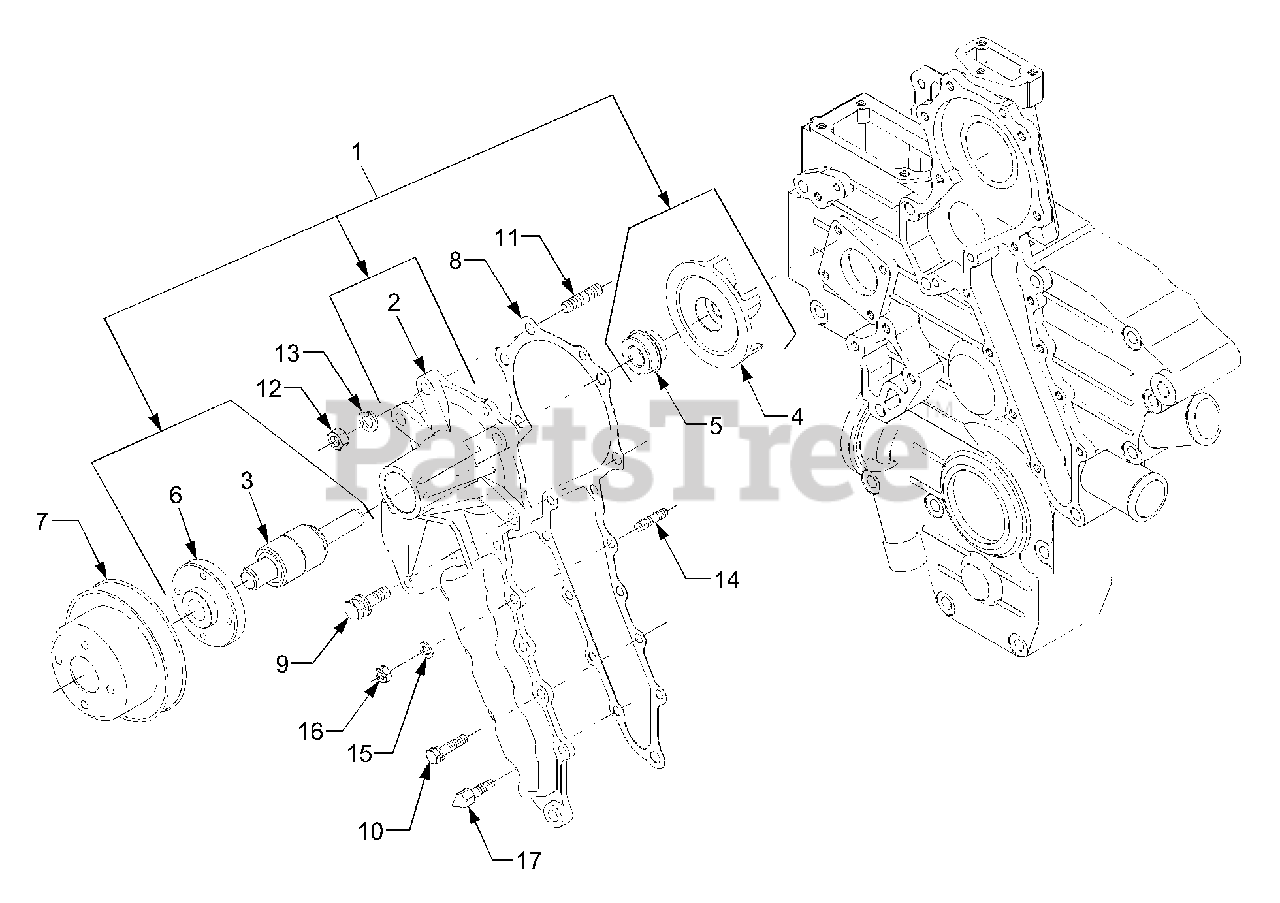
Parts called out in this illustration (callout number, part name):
1	Water Pump Ass'y
2	Body, Water Pump
3	Bearing, Water Pump
4	Impeller, Water Pump
13	Washer, Spring
15	Washer, Spring
